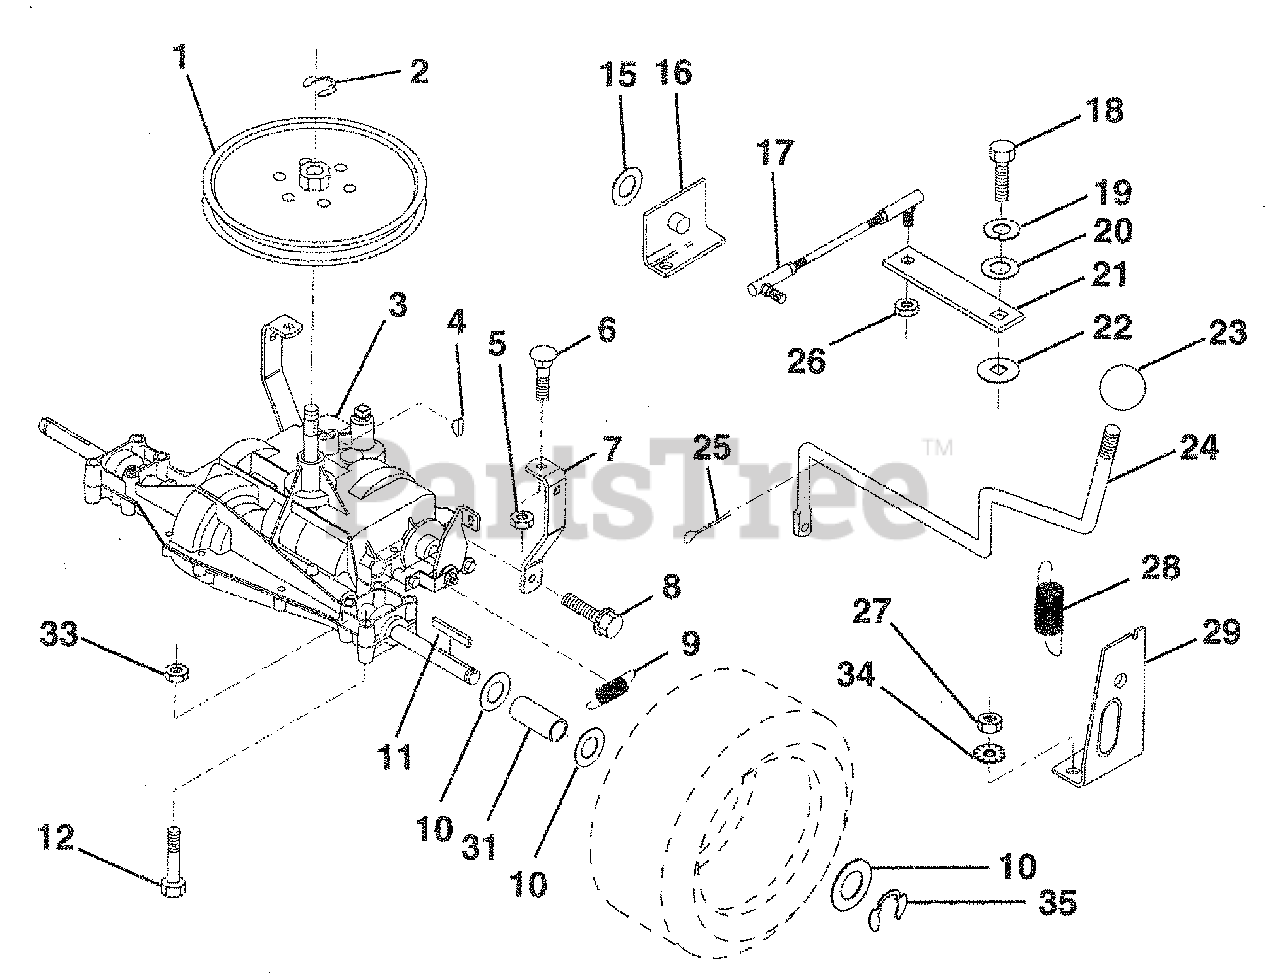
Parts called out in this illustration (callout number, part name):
2	Ring, Retainer
3	Transaxle, 5 Speed, Dana Model #4360-50
4	Key, Woodruff #9
5	Nut, Crownlock 5/16-18
6	Bolt, Carriage 5/16-18 UNC x 3/4
7	Strap, Torque
8	Screw Thdrol. 5/16-18 x 3/4
9	Spring, Brake
10	Washer 25/32 x 1-1/4 x 16 Ga.
11	Key, Square
12	Bolt Hex 3/8-16 x 2-3/4
15	Washer 17/32 x 1 x 16 Ga
16	Support Handle Shift LH
17	Link, Shift
18	Bolt, Fin Hex 1/4-28 U NF x 3/4 Gr. 8
19	Washer, Lock 1/4
20	Washer 9/32 x 3/4 x 10 Ga.
21	Arm, Shift
22	Washer, Shift Plate
24	Handle, Shift Rod
25	Pin, Cotter 1/8 x 1
26	Nut, Hex Nylon
27	Nut, Keps 5/16-18
28	Extension, Spring
29	Support Handle Shift RH
31	Spacer, Split
33	Nut, Crownlock 3/8 -16
34	Washer, Ext., Tooth, Lock 5/16
